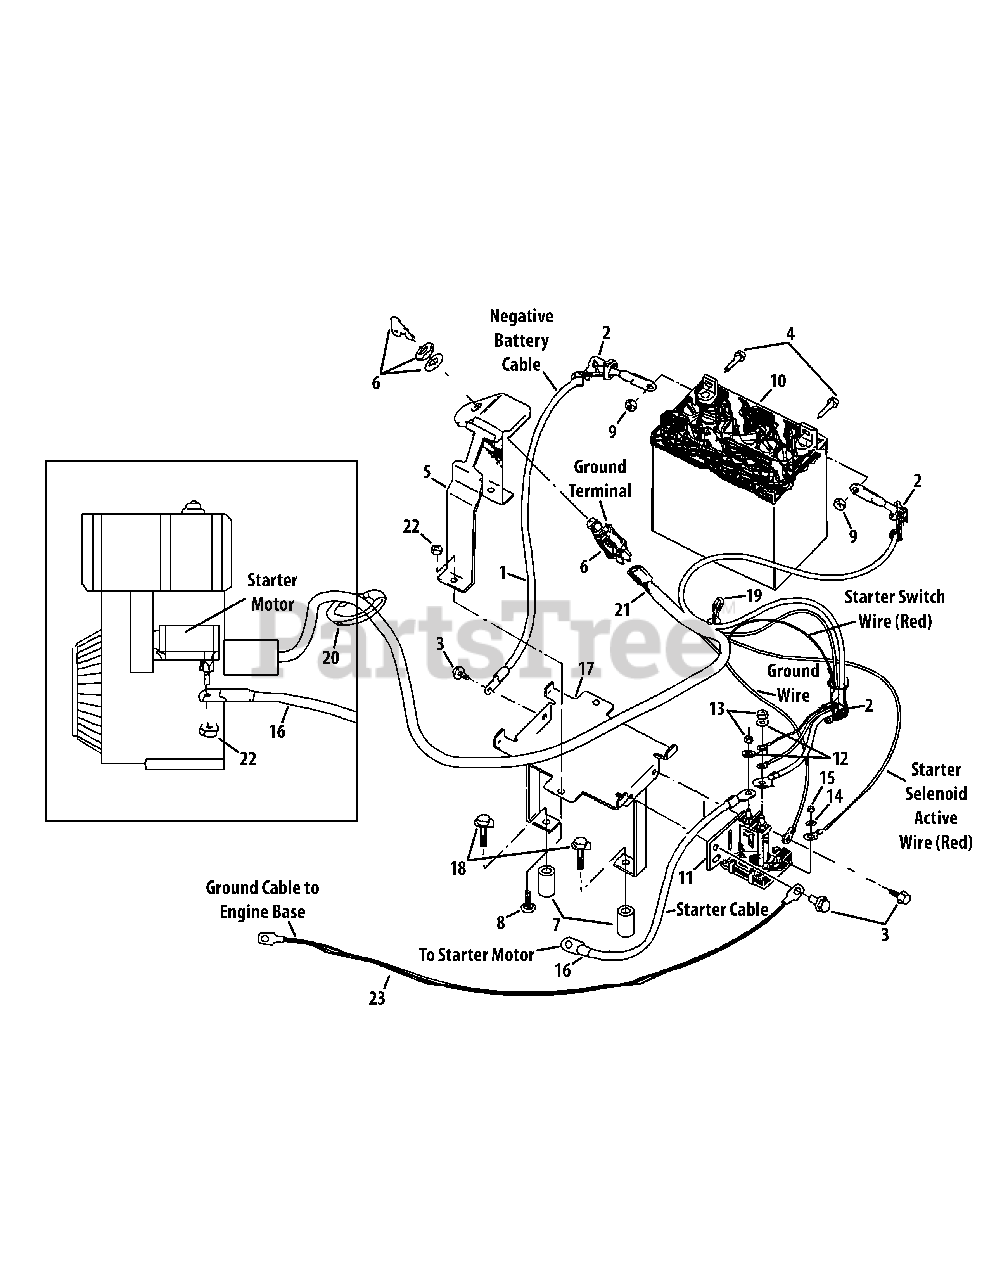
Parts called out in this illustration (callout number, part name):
1	Battery Cable
2	Terminal Insulating Boot
3	TT-Screw, 1/4"-2 x 1/2"
4	Hex Bolt, 1/4"-20 x 5/8"
5	Battery Hold-down Clamp w/ Att Key Switch Plate
6	Key Switch (Incl 2 Keys)
8	Carriage Bolt, 1/4"-20 x 1-1/4"
9	Hex Nut, 1/4"-20
10	12-Volt Battery
11	Starter Solenoid
12	Lockwasher, 5/16"
13	Hex Nut, 5/16"-24
14	External Tooth Lockwasher
15	Hex Nut, #10-32
16	Battery Cable
17	Battery Bracket
18	Hex Head Screw, 3/8"-16 x 275"
19	Plastic Tie
20	Plastic Tie
21	Wire Harness & Connecting Terminal Assembly
22	Flangelock Nut, 1/4"-20
23	Ground Cable
